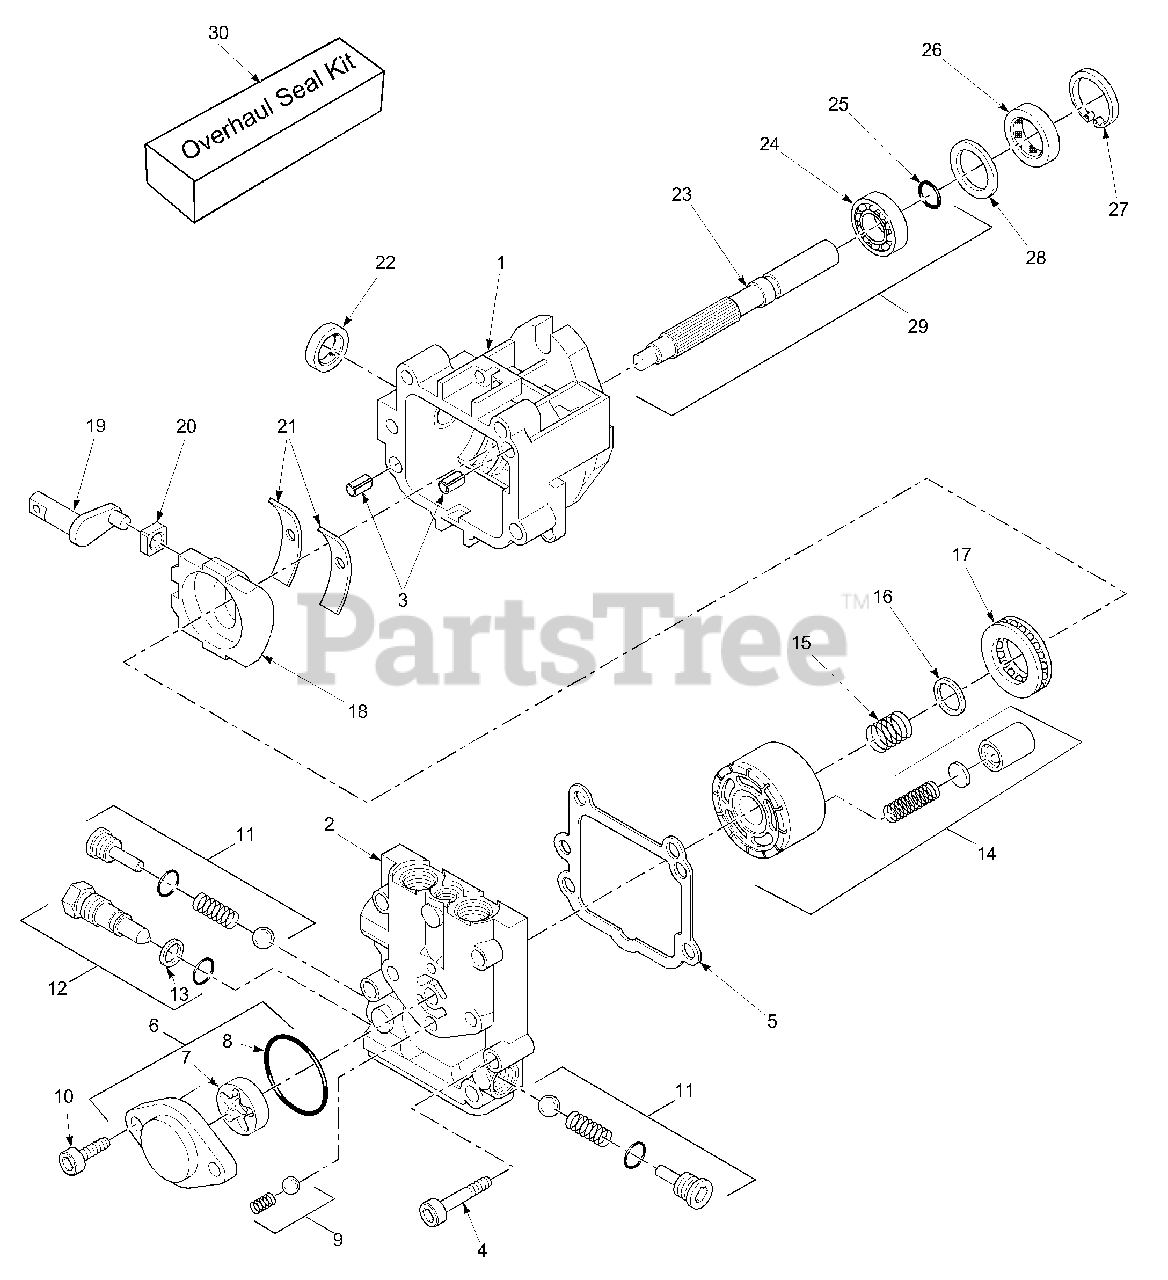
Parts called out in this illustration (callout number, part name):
1	Housing Kit
2	End Cap
3	Straight Headless Pin
4	Socket Head Screw
5	End Cap Gasket
6	Charge Pump Kit
7	Gerotor Assembly
9	Charge Relief Valve Kit
10	Socket Head Screw
11	Check Valve Kit
12	Bypass Valve Kit
13	Backup Ring
14	Cylinder Block Kit
15	Block Spring
16	Block Thrust Washer
17	Roller Thrust Bearing
18	Swash Plate
19	Trunnion Arm
20	Guide Slot
21	Cradle Bearing
23	Pump Shaft
24	Ball Bearing
25	Retaining Ring
27	Retaining Ring
29	Shaft Kit
30	Overhaul Seal Kit
